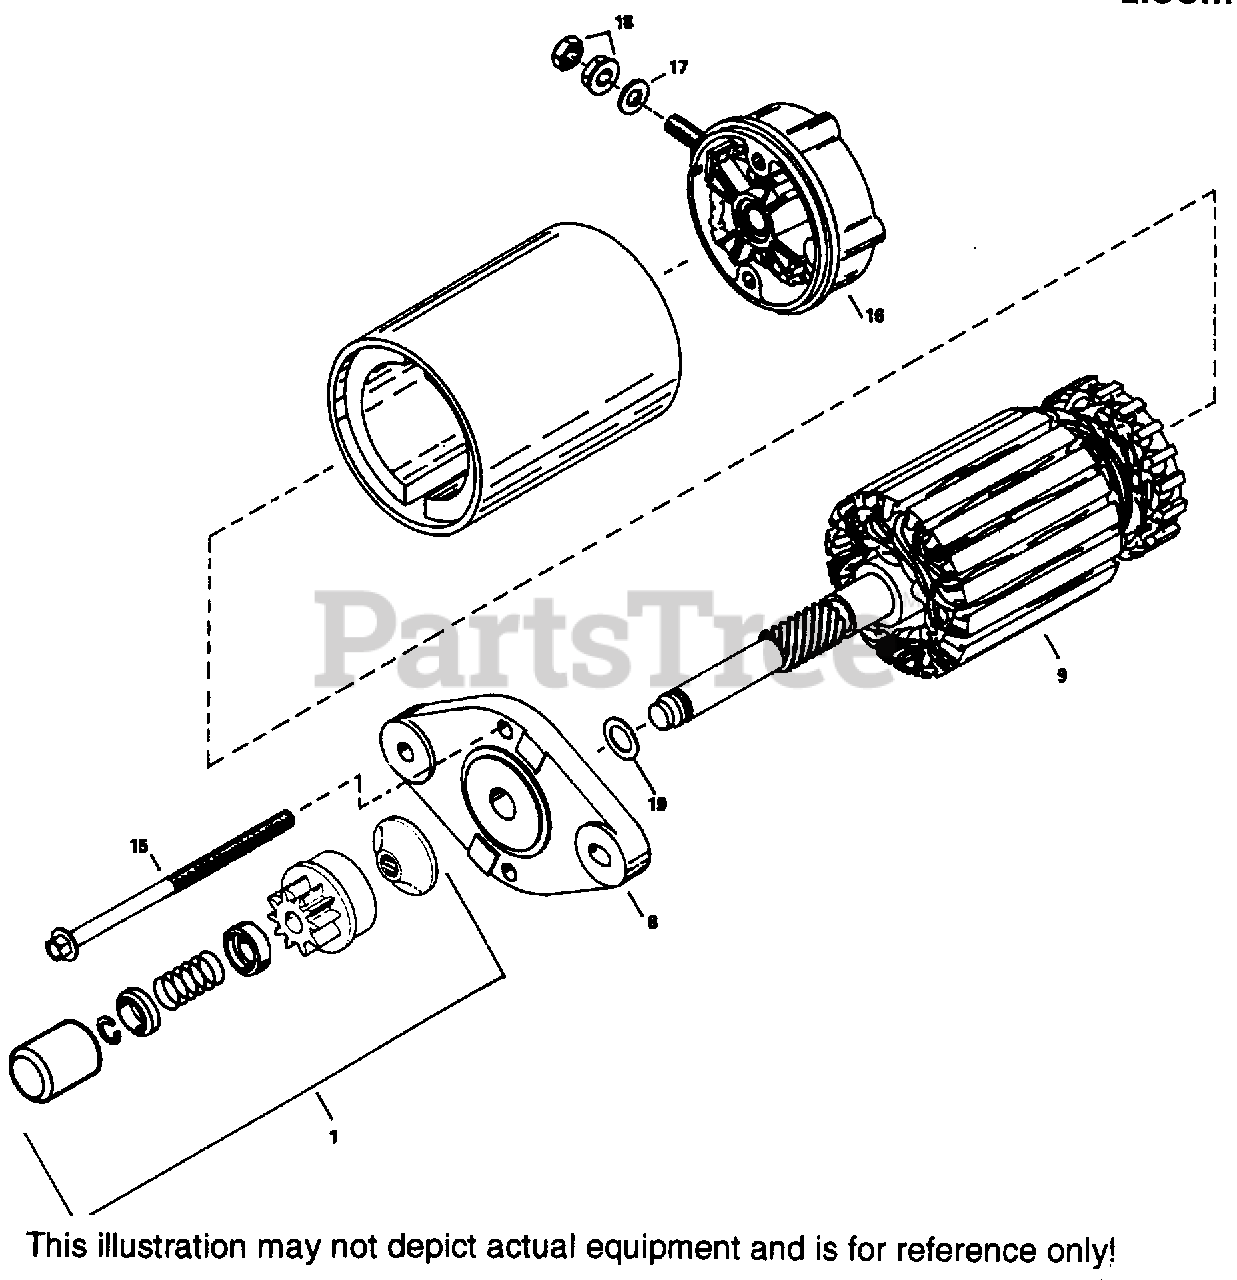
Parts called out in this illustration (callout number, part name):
1	Drive Kit
8	Drive End Cap Ass'y.
9	Armature
15	Case Bolt
16	Commutator End Cap & Brush Card Ass'y .
19	Thrust Washer
